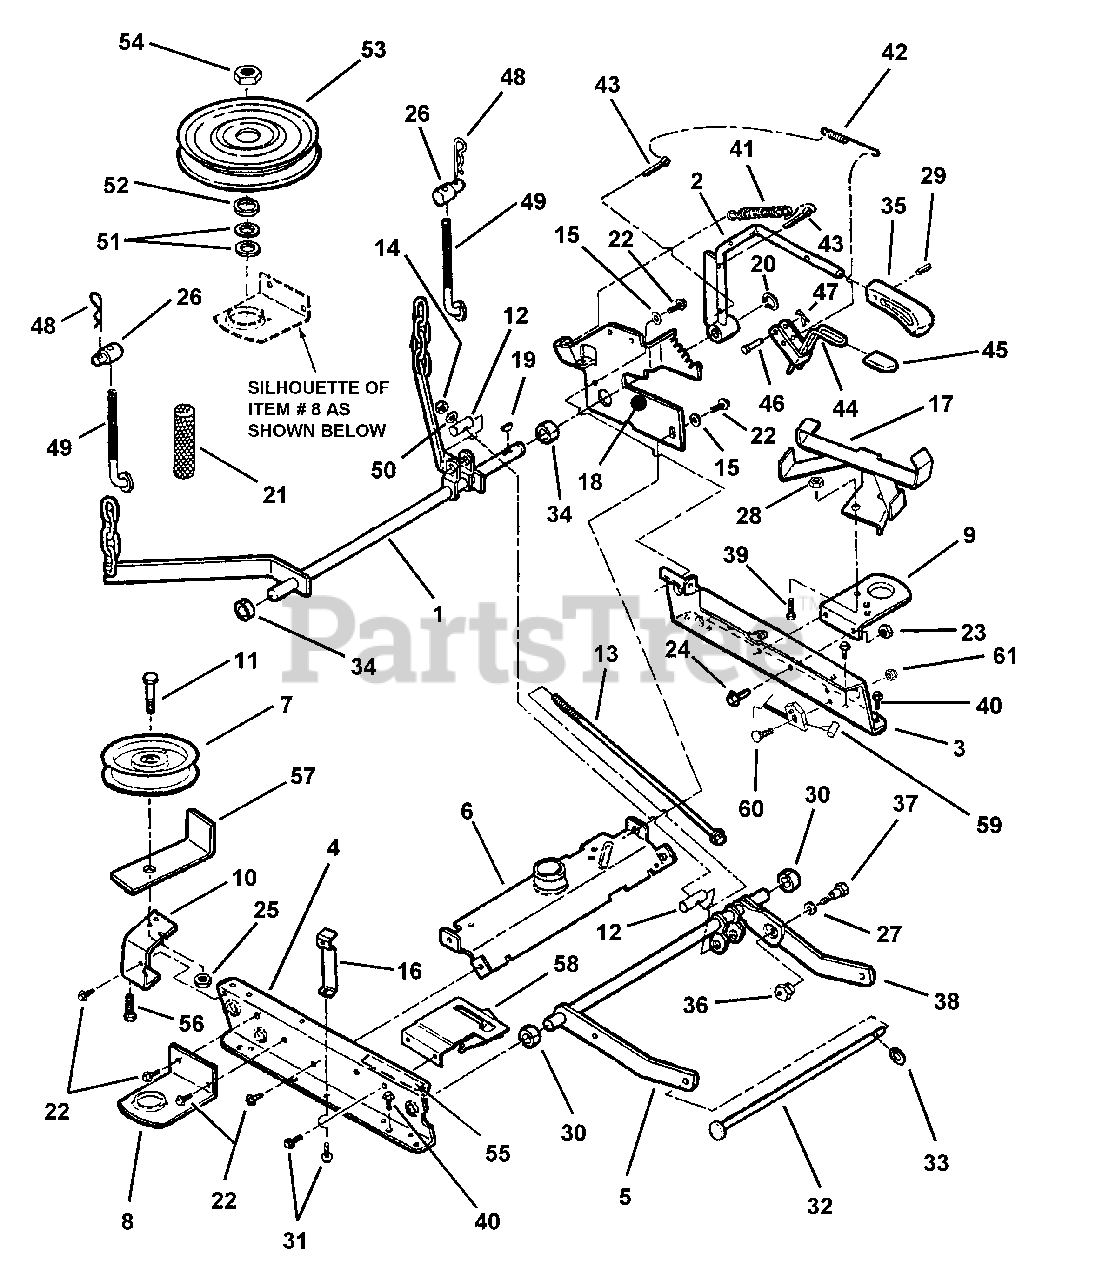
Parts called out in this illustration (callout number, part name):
1	ASSEMBLY, Rear Lift Arm
2	LEVER, Height Adjustment Lift
3	RAIL, Left Half
4	RAIL, Right Half
5	STRUCTURE, Front Lift Arm
6	BRACE, Weldment
7	IDLER, 4-1/8" Flat
8	SPINDLE, Brace (Right)
9	SPINDLE, Brace (Left)
10	BRACKET, Cover
11	SCREW, 3/8-16 x 1-1/2" Hex Head Cap
12	PIVOT
13	ROD, Leveling
14	NUT, 3/8-24 Hex Top Lock
15	WASHER, 3/8 Internal Tooth Lock
16	GUIDE, Belt (Rod)
17	GUIDE, Belt, 42" RER
18	QUADRANT, Lift Lever
19	KEY, 3/16 x 7/8" Woodruff
20	RING, 3/4 Retaining
21	COVER, Chain
22	SCREW, 3/8-16 x 3/4" Self-Tapping
23	NUT, 3/8-16 Hex Center Lock
24	SCREW, 3/8-16 x 3/4" Hex Head Cap, Grade 5
25	NUT, 3/8-16 Hex Nyloc
26	SWIVEL, Adjustable
27	WASHER, 3/8 Internal Tooth Lock
28	NUT, 3/8-24 Hex Lock
29	PIN, 3/16 x 3/4" Roll
30	RING, Red
31	SCREW, 5/16-18 x 1/2" Hex Washer Self-Tap
32	SUPPORT, Rod
33	RING, Retaining
34	RING, Blue
35	GRIP, Height Adjustment Lever
36	ECCENTRIC, Leveling
37	BOLT, 3/8-24 x 3/4" Shoulder
38	ARM, Front Lift (Left Side)
39	BOLT, 3/8-16 x 1" Hex Flange Lock
40	BOLT, 5/16-18 x 5/8" Hex Flange Lock
41	SPRING, Extension
42	SPRING, Latch
43	COTTER-PIN, 3/16 x 1-1/2"
44	LATCH
45	GRIP, Lift Latch
46	PIN, 1/4 x 1-1/4" Clevis
47	COTTER-PIN, 1/16 x 3/4"
48	HAIRPIN, 3/32 x 1-1/2"
49	ADJUSTER, Chain
50	WASHER, 3/8" Flat
51	WASHER, 3/4 Flat
52	SPACER, 3/4" I.D.
53	PULLEY, 5" O.D.
54	NUT, 3/4-16 Hex Jam
55	DECAL, Blade ON/OFF
56	BOLT, 5/16-18 x 5/8" Hex Washer Head, Self-Tap
57	GUIDE, Belt
58	ASSEMBLY, Clutch Plate
59	CABLE, No-Reverse-In-Mow
60	BOLT, #10-24 x 1" Flat Head Square Neck
61	NUT, #10-24 Hex Nyloc
